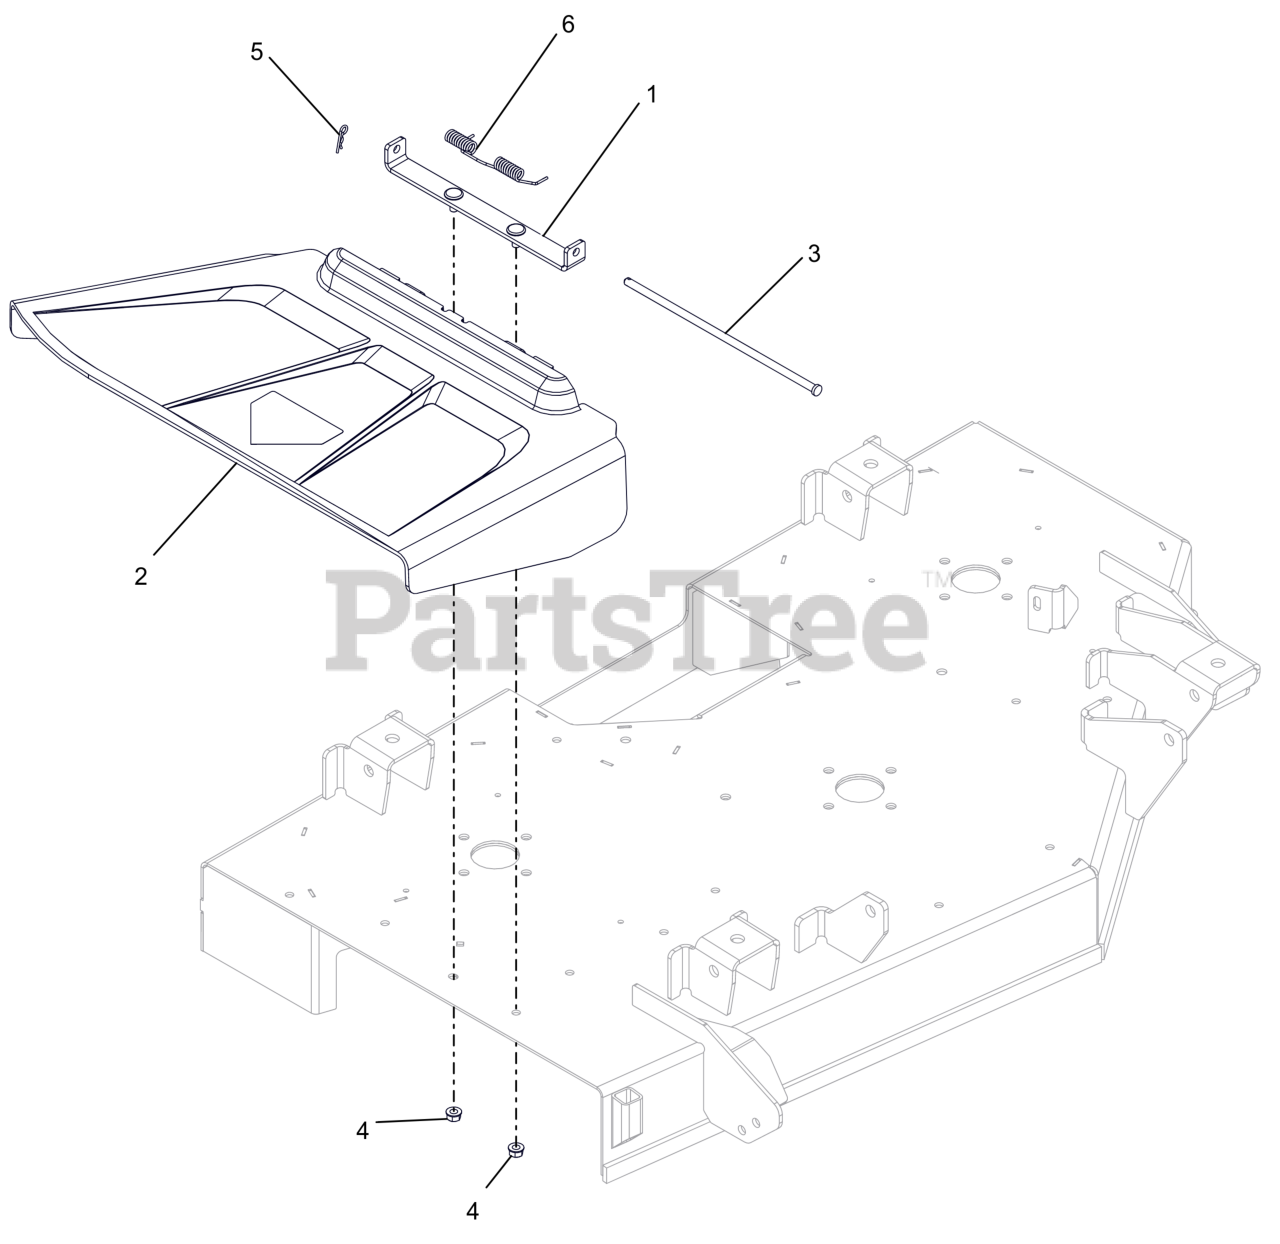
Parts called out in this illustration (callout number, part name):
2	CHUTE, SIDE DISCHARGE
3	PIN, 5/16 X 10.5
4	NUT-LK-TOP-FLG .312-18 GF ZCC
5	PIN, HAIR #213 .08X1.19 ZCC
6	SPRING-TORSION
